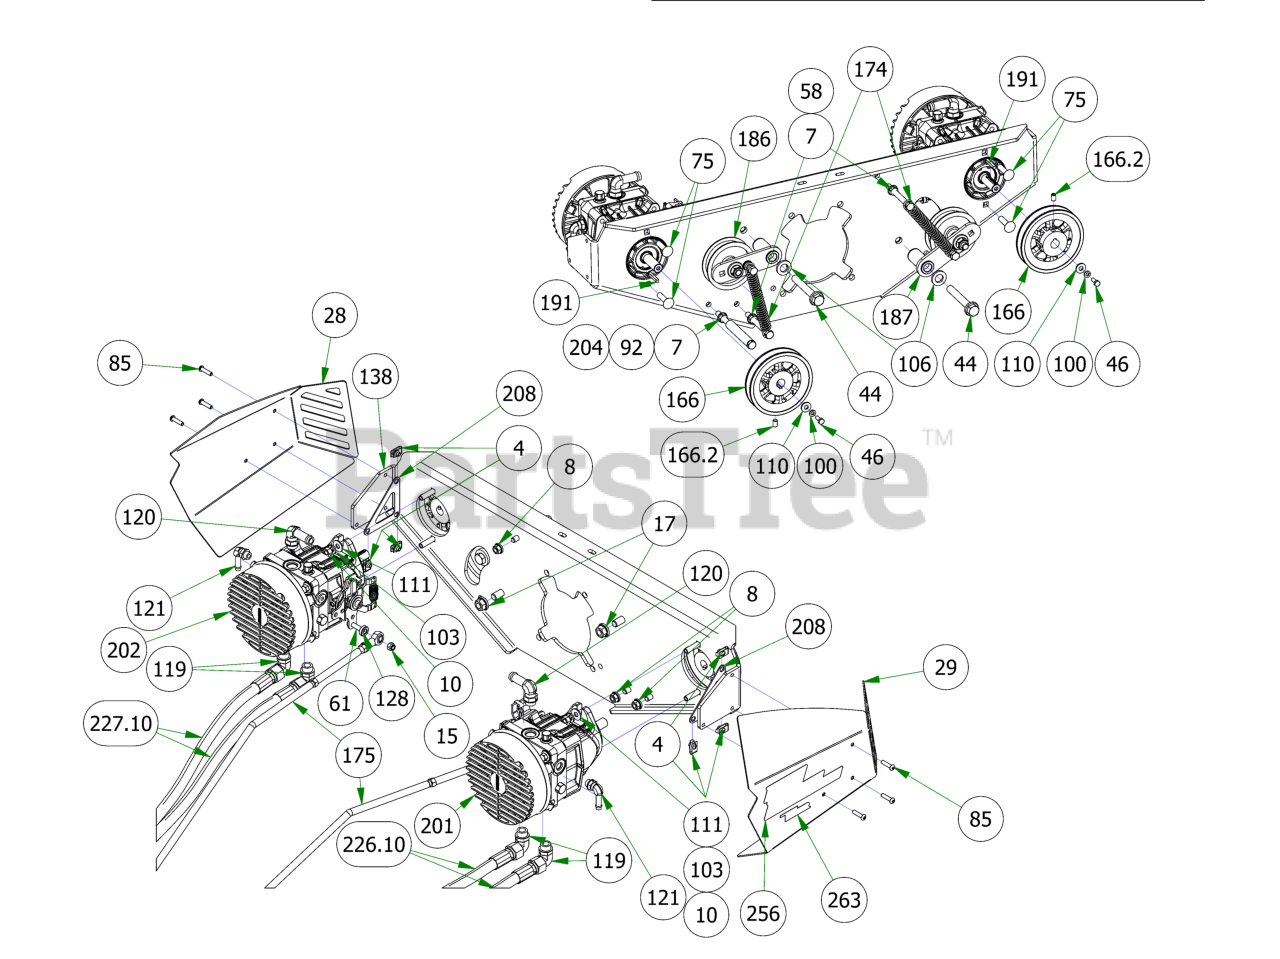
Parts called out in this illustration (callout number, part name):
4	1/4-20 Cage Nut
7	3/8-16 HEX SERRATED FLANGE NUT HARD/ZINC
8	3/8-16 NYLON INSERT FLANGE LOCKNUT (GR.F) ZINC
10	3/8-16 HEX NUT ZINC
15	5/16-18 NYL INS L/N ZC
17	1/2-13 NYLON INSERT FLANGE LOCKNUT ZINC
28	2019 Horizontal Pump Cover - Right - Black
29	2019 Horizontal Pump Cover - Left - Black
44	1/2-13 X 90MM HEX FLANGE BOLT W/SHOULDER (GR.8) ZINC
46	M6-1.0 X 16MM DIN 933 HEX TAP BOLT (CL 8.8) ZINC
58	3/8-16 X 3-1/2 HEX CAP SCREW (GR.5) ZINC
61	5/16-18 X 1-1/4 HEX C/S (GR.5) ZC
75	3/8-16 X 1-1/2 CARRIAGE BOLT ZINC
85	1/4-20 x 1" BS C/S 18-8 SS
92	3/8-16 X 5-1/2 HEX CAP SCREW (GR.5) ZINC
100	1/4 SPLIT LOCKWASHER ZINC
103	3/8 SPLIT LOCKWASHER ZINC
106	.635 ID X 1.120 OD X .140 THICK FLAT WASHER NYLON
110	1/4 USS FLAT WASHER (3/4 OD) ZINC
111	5/16 USS FLAT WASHER (7/8 OD) ZINC
119	2019 Outlaw 90 Degree Pump Fitting #6801-10-08
120	90 Degree Fitting, 1/2 x 3/4, 4601-8-8
121	90 Degree Fitting, 3/8 s 9/16
128	ACS Spacer 3/4x3/8x1/4
138	Pump Plate - 2019 Horizontal Gas-Orange
166	5" PUMP PULLEY W/ SET SCREW
166.2	5/16-24 X 1/2 SOCKET SET SCREW KNURLED CUP POINT
174	ZT and ACS Handle Spring
175	2019 Renegade Push Rod Assembly
186	2019 Renegade Belt Tensioner LH
187	2019 Renegade Pump Belt Tensioner RH
191	5MM X 36MM SQ MACHINERY KEY C1018 ROUNDED ENDS
201	2019 Rogue/Renegade Left Pump 16cc
202	2019 Outlaw Renegade Right Pump 16cc
204	3/8 hose 4" long
208	Pump Plate Clip Nut Holder
226.10	2019 Renegade Hydro Hose
227.10	2019 Renegade Hydro Hose
256	999cc EFI Decal Cluster
263	2022 Powered By Kohler Decal
